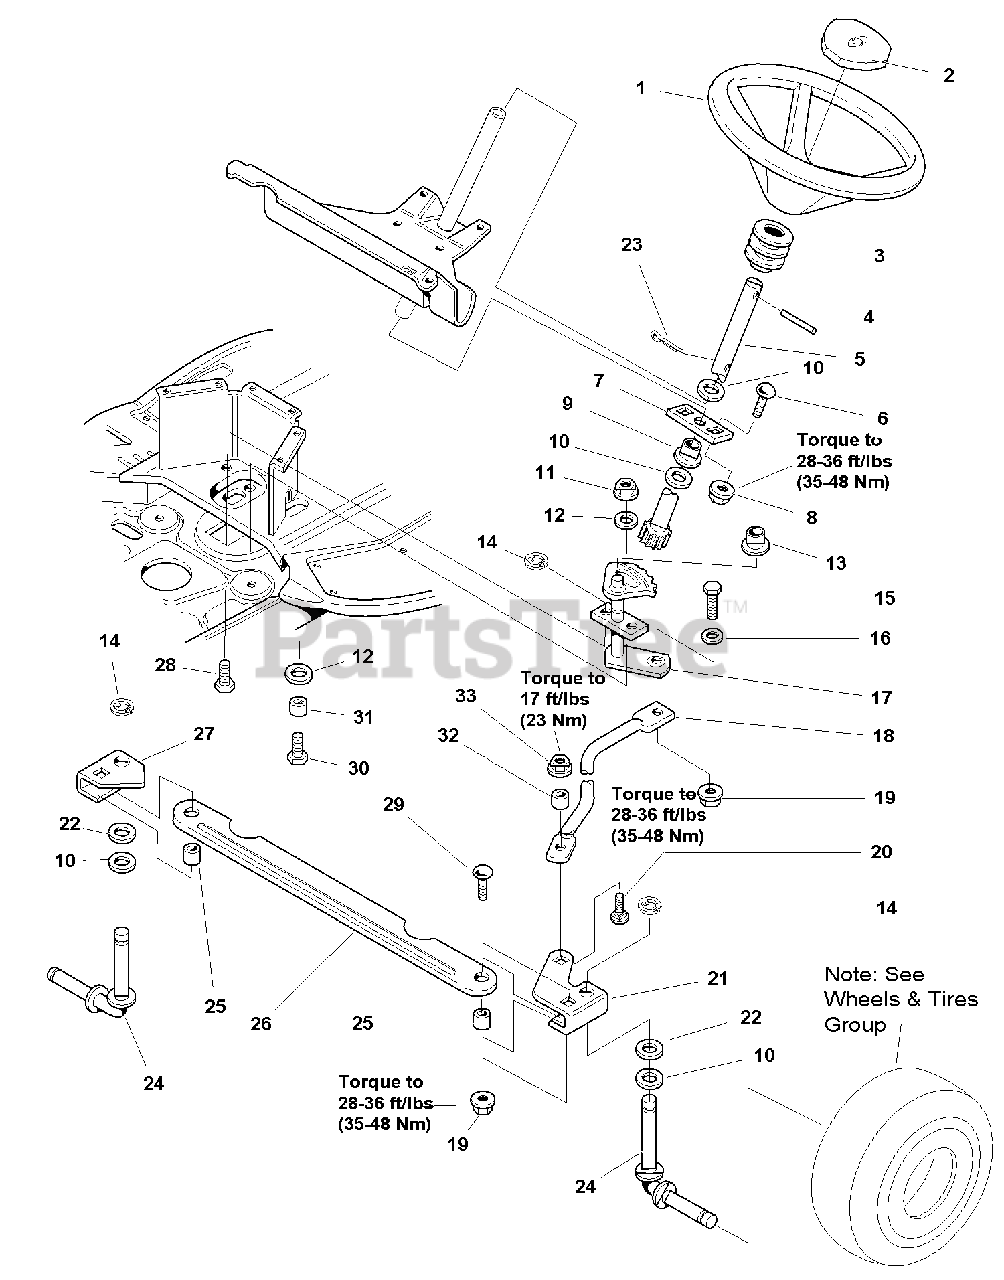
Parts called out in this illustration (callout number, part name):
1	STEERING WHEEL
2	CAP, Steering Wheel, Simplicity
4	PIN, Spring
5	SHAFT & PINION ASSEMBLY
6	CARRIAGE BOLT, 3/8-16 x 1
7	PLATE, Mounting
8	NUT, Hex Head Whiz Lock, 3/8-16
10	WASHER
11	NUT, Hex Lock, 5/16-18
14	RING, Clipring Extension
15	CAPSCREW, Hex Head, 3/8-16 x 1-1/4
17	STEERING GEAR ASSEMBLY
18	LINK, 19.66" Long
19	NUT, Hex Flange Lock, 3/8-16
20	CARRIAGE BOLT, 5/16-18 x 1
21	ARM & SPACER ASSEMBLYMY, LH Splined
23	PIN, Cotter
24	SPINDLE & CUP ASSEMBLY
27	ARM & SPACER ASSEMBLY, RH
28	CAPSCREW, Hex Head, Taptite, 5/16-18 x 3/4
29	CARRIAGE BOLT, 3/8-16 x 1-1/4
30	CAPSCREW, Hex Head, 5/16-18 x 1-1/2
33	NUT, Hex Flange Lock, 5/16-18
